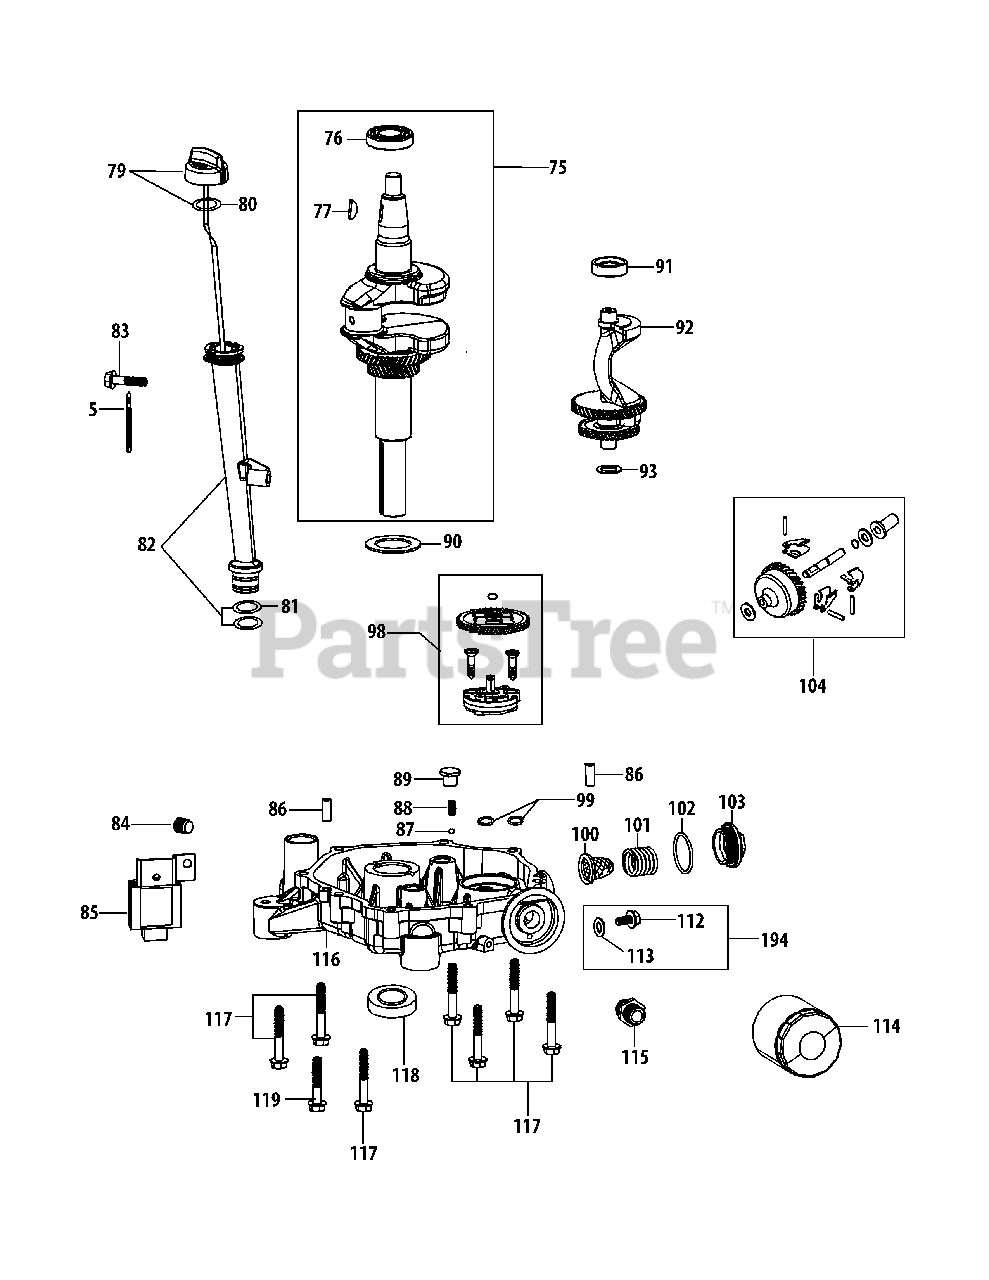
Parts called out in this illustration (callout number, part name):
5	Flexible Clamp
75	Crankshaft Assembly
76	Main Bearing
77	Woodruff Key
79	Dipstick Assembly
80	Upper O-Ring
81	Lower O-Ring
82	Oil Fill Tube Assembly
83	Bolt M6×35
84	Oil Drain Plug
86	Dowel Pin 8×14
90	Crankshaft Thrust Washer
91	Balanceable Shaft Bearing
92	Balanceable Shaft Assembly
93	Balanceable Thrust Washer
98	Oil Pump Assembly
99	O-Ring 10×2.65
101	Filter Spring
102	O-Ring 35.5×2.65
103	Filter Cover
104	Governor Gear/Shaft Assembly
112	Bolt M8×15
113	Oil Drain Plug Washer
114	Oil Filter
115	Screw Joint
116	Crankcase Cover
116	Crankcase Cover Asm
117	Bolt M8×54
118	Lower Crankshaft Seal
119	Bolt M8×43
194	Oil Drain Plug Assembly
